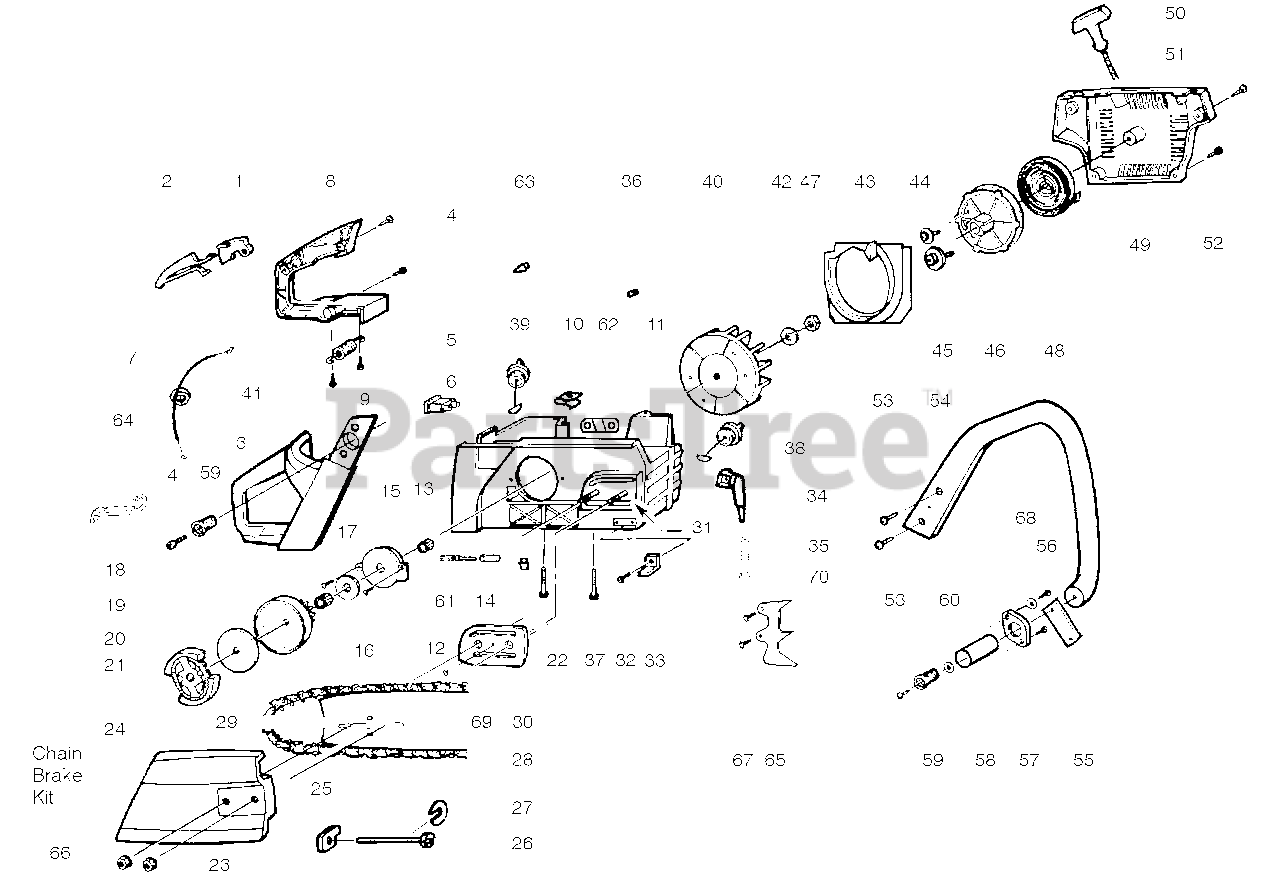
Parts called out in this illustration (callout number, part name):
1	Throttle Trigger
2	Throttle Lockout
3	Rear Pro Handle
5	Isolator Spring
7	Throttle Cable
8	Handle Cover
9	Ignition Switch
10	Speed Nut
11	Chassis Ass'y. 255,310
11	Chassis Ass'y. 315
12	Oil Pump Ass'y.
13	Oil Pump Worm
14	Oil Pump Barrel
15	Oil Pump Hsg.
17	Thrust Washer
18	Clutch Bearing
19	Clutch Drum 255 U.S
19	Clutch Drum 310 & 315
20	Clutch Washer
21	Clutch Ass'y.
22	Oil Seal
23	Bar Mounting Nut
25	Bar Adjusting Pin
27	Chain 310, 315-16"
27	Chain 310, 315-18"
27	Bar 310-16"
27	Bar 315-18"
30	Bar Plate
31	Bar Bolt
33	Chain Catcher
34	Oil Pick-up
35	Oil Filter
36	Vent Plug
38	Oil Cap Ass'y.
39	Fuel Cap Ass'y.
39	Flywheel Ass'y. 310 & 315
42	Baffle Plate 310 & 315
46	Starter Pulley
48	Recoil Spring
48	Fan Hsg. Ass'y. Kit 310
50	Starter Handle
51	Rope Kit
53	Handle, 310, 315
55	Front Strap
56	Plate Screw
57	Isolator Plate
58	Spring Sleeve
59	Isolator Spring
61	Plunger & Gear Ass'y.
62	Bar Stud Plate
63	Check Valve
64	Choke Lever
65	Spike Ass'y.
66	Chain Brake Ass'y 255, 310
70	Plug-Oiler Filter
